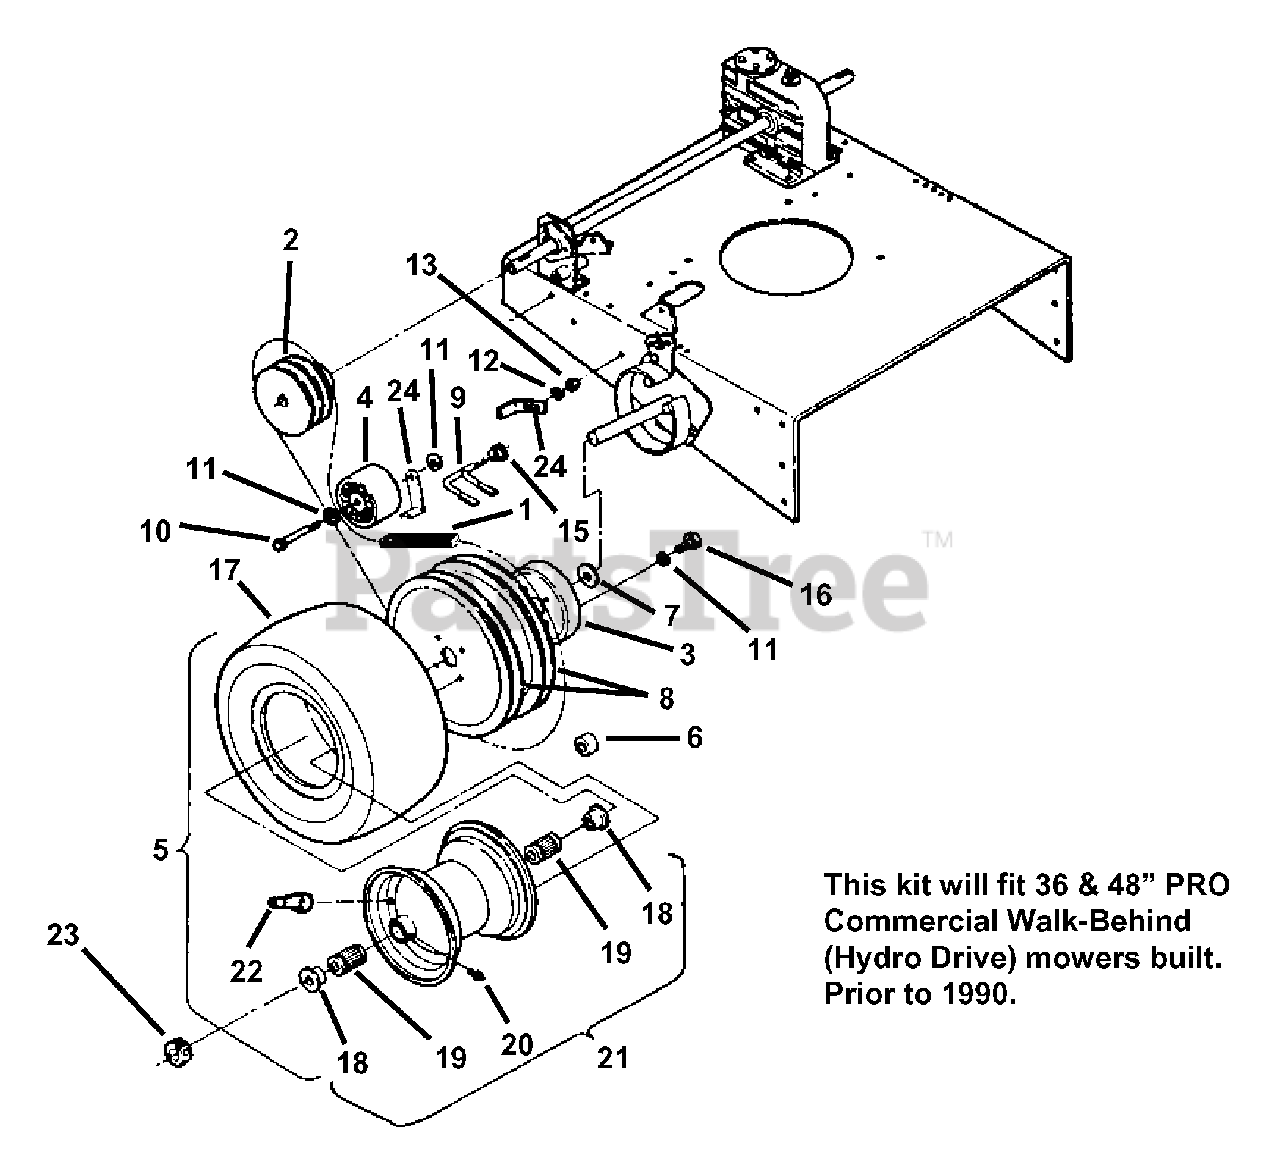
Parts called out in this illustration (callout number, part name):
1	BELT, Traction (Dual Band)
2	PULLEY, Output
3	HUB, Brake
4	PULLEY, Idler
5	ASSEMBLY, Wheel
6	SPACER
7	BUSHING, 7/8"
8	PULLEY, Traction
9	SCRAPER
10	SCREW, 3/8-24 x 1-3/4" Hex Head Cap, Grade 5
11	WASHER, 3/8" Split Lock
12	WASHER, 5/16" Split Lock
13	NUT, 5/16" Hex, Gr. 5 or B
15	NUT, 5/16-18 Flange Lock
16	SCREW, 3/8-24 x 1-1/2" Hex Head Cap, Grade 5
17	TIRE, 13 x 6.50-6 (4 Ply)
18	BUSHING, Flange
19	BEARING, Roller
20	FITTING, Lube, 1/4-28, Straight
21	ASSEMBLY, RIM, w/Flange
22	STEM, Air Valve
23	COLLAR CLAMP w/Set Screw
24	GUIDE, Belt
